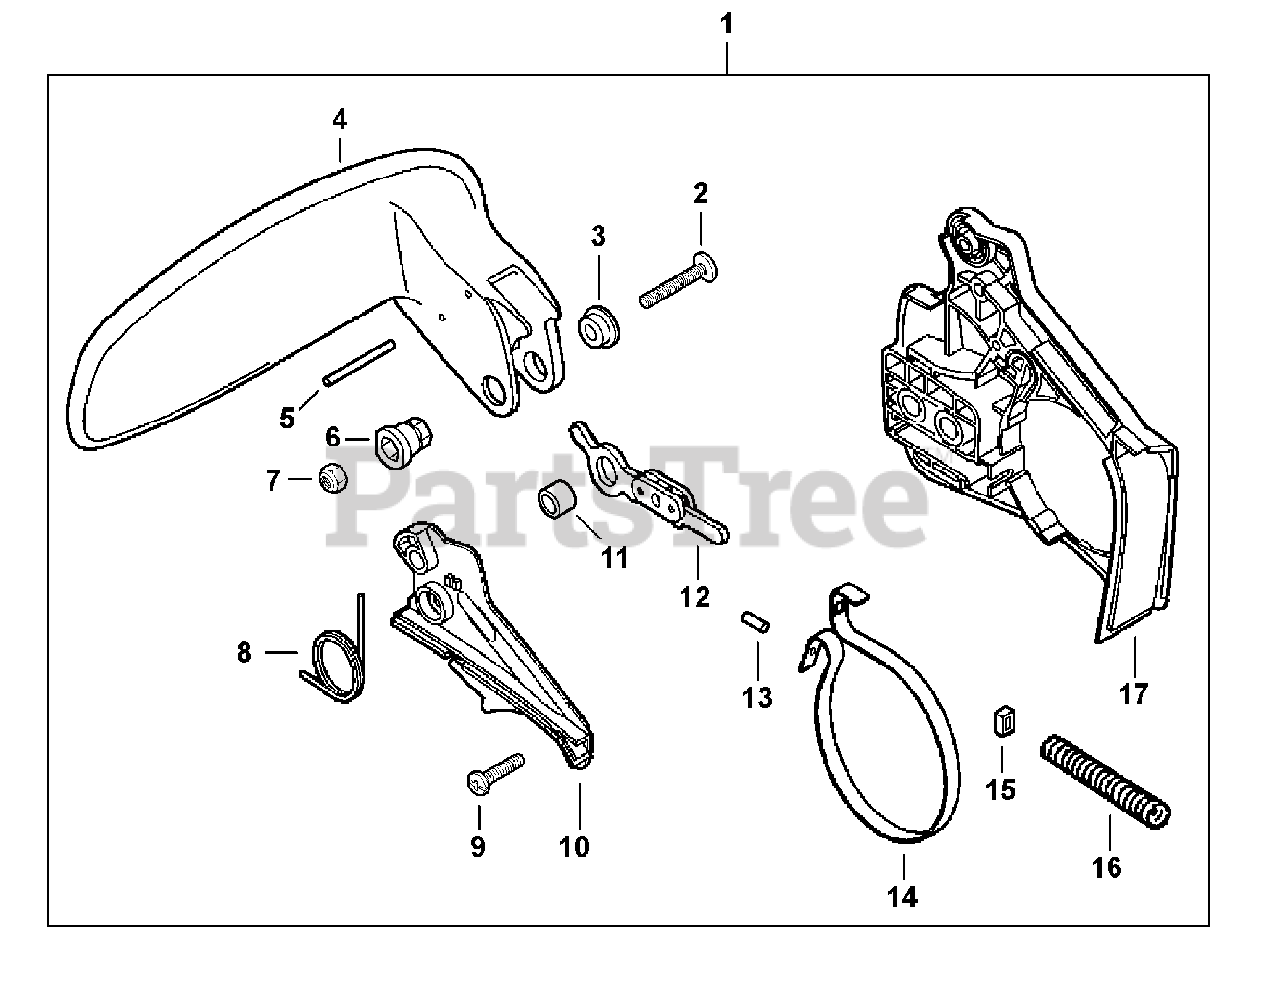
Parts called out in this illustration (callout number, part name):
1	CHAIN BRAKE ASSY - GRAY
2	SCREW - 5X32
4	LEVER, BRAKE - ORANGE
5	PIN - 3X26
6	COLLAR - 5
7	LOCKNUT - 5
9	SCREW - 4X12 -- TAPPING
10	COVER, BRAKE
11	SPACER - 8
12	CONNECTOR, BRAKE
13	PIN - SPRING
14	BAND, BRAKE
17	GUARD, SPROCKET
